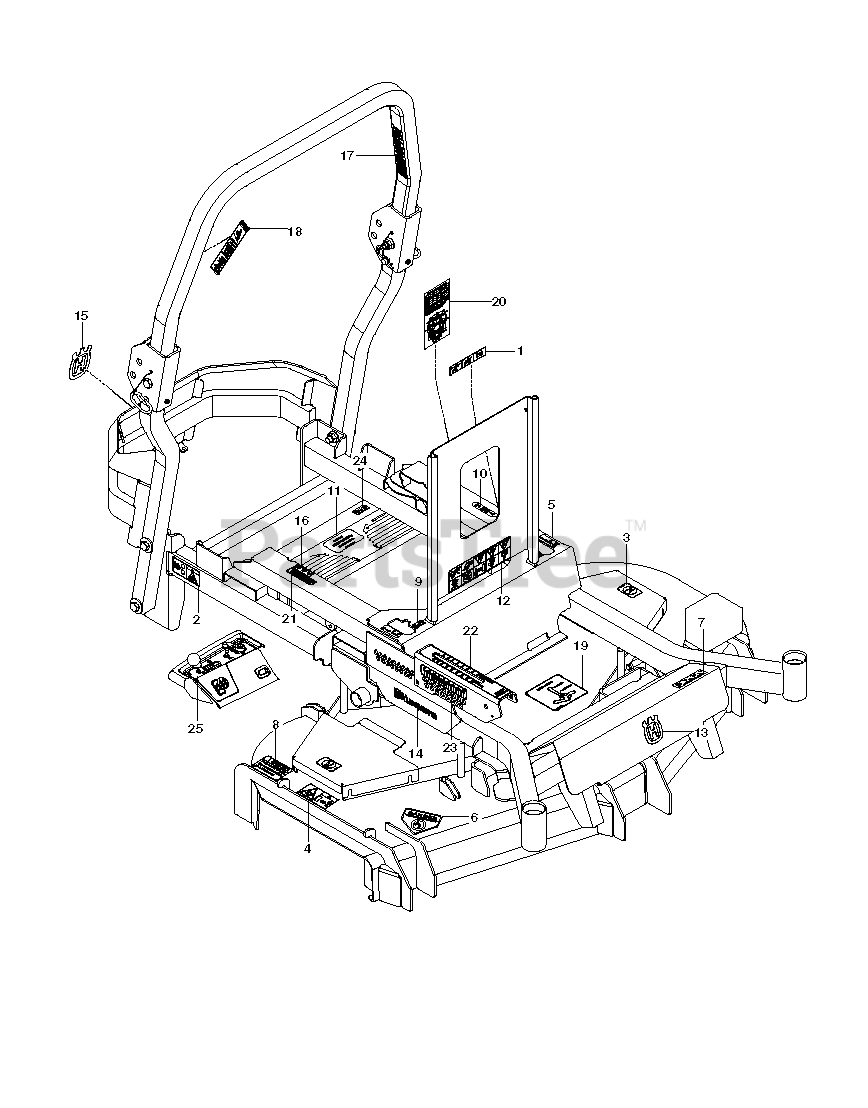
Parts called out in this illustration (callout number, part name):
1	EURO DECAL-BATTERY WARNIN6
2	DECAL, BELT DRIVE
3	DECAL, NO STEP
4	DECAL, EURO SEVERING
5	DECAL, MOTION CONTROL
6	DECAL, CPSC
7	DECAL.ZTRPZ54.HUSQVARNA
8	DECAL, CAUTION
9	DECAL, F.S.T.
10	DECAL, PARK BRAKE
11	DECAL, OIL TANK
12	DECAL, WARNING
13	DECAL.AUGER.HUSQ.CROWN.SNOW
14	RP.DECAL.BADGE.170MM.TEXTLOGO
15	DECAL, CROWN H, 110MM
16	DECAL, FUSE
17	DECAL, ROPS
18	DECAL, ROPS, WARNING
19	DECAL, BELT ROUTING
20	DECAL, SERVICE
21	DECAL, WARNING SPARK ARRESTOR
22	DECAL, HEIGHT
23	DECAL, HEIGHT
24	DECAL, FUEL
25	DECAL, CONTROL, GAS
